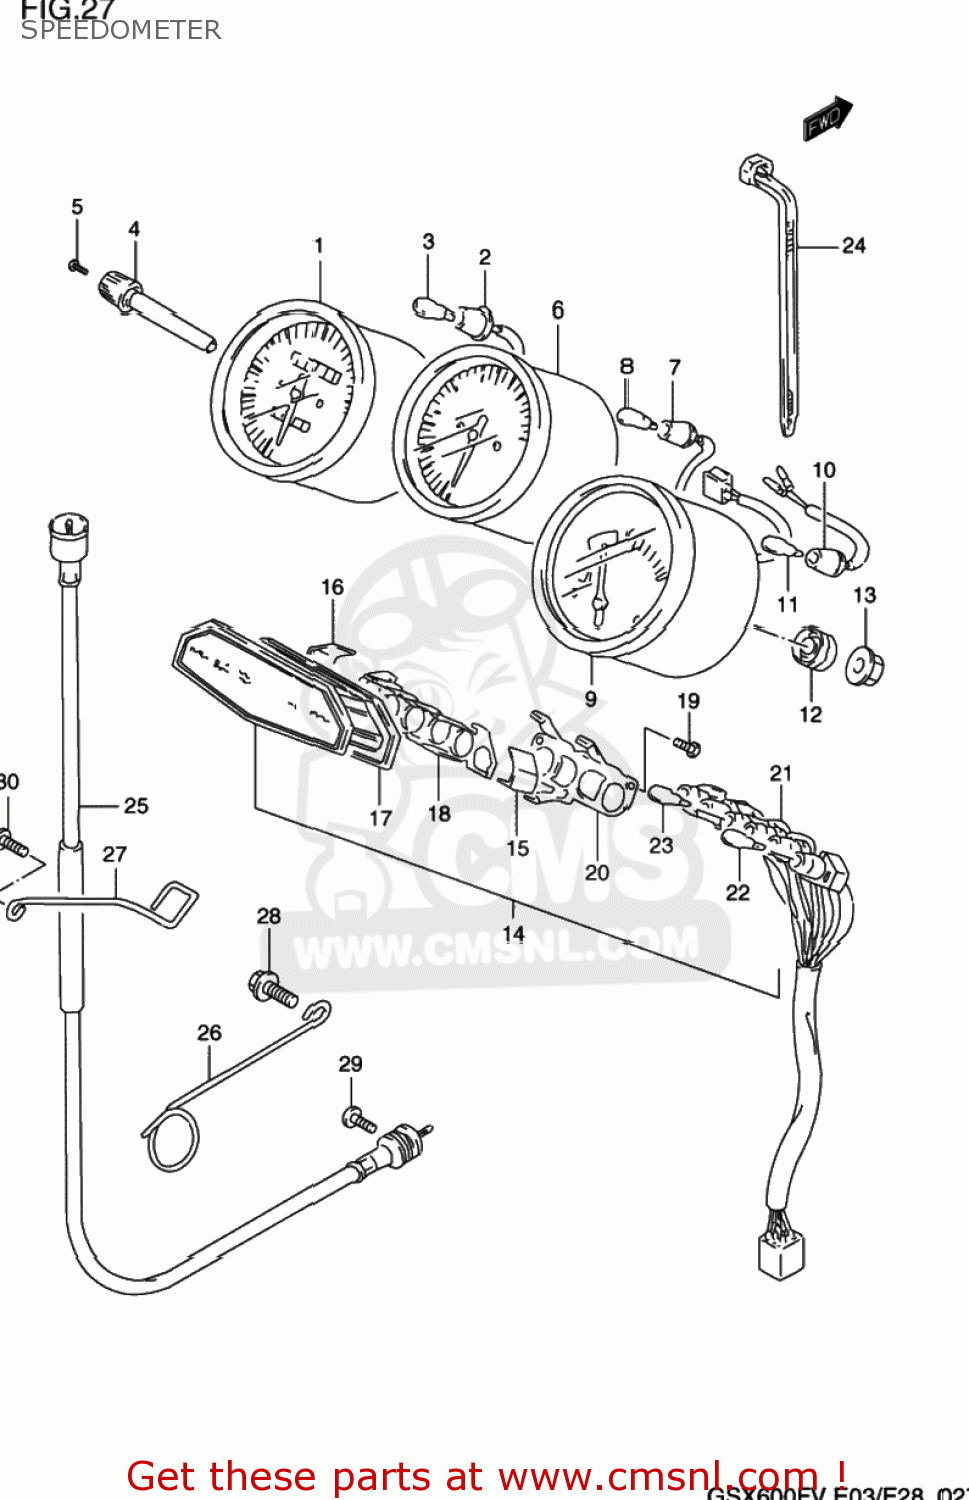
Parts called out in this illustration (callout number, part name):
1	SPEEDOMETER ASSY
2	SOCKET
3	BULB(12V3W,WB371,T7)
4	KNOB,TRIP
5	SCREW,TRIP KNOB
6	TACHOMETER ASSY
7	SOCKET
8	BULB(12V3W,WB371,T7)
9	FUEL,METER ASSY
10	SOCKET
11	BULB(12V3W,WB371,T7)
12	CUSHION
13	NUT
14	BOX ASSY
15	PLATE,TURN,R
16	PLATE,TURN,L
17	CUSHION
18	PLATE,PILOT LAMP
19	SCREW
20	LOCK PLATE
21	SOCKET
22	BULB(12V1.7W,WB372,T7)
23	BULB(12V3W,WB371,T7)
24	CLAMP(L:125)
25	CABLE ASSY,SPEEDOMETER
26	CLAMP,SPEEDOMETER CABLE
27	CLAMP,SPEEDOMETER CABLE
28	BOLT
29	SCREW
30	SCREW 5X12
